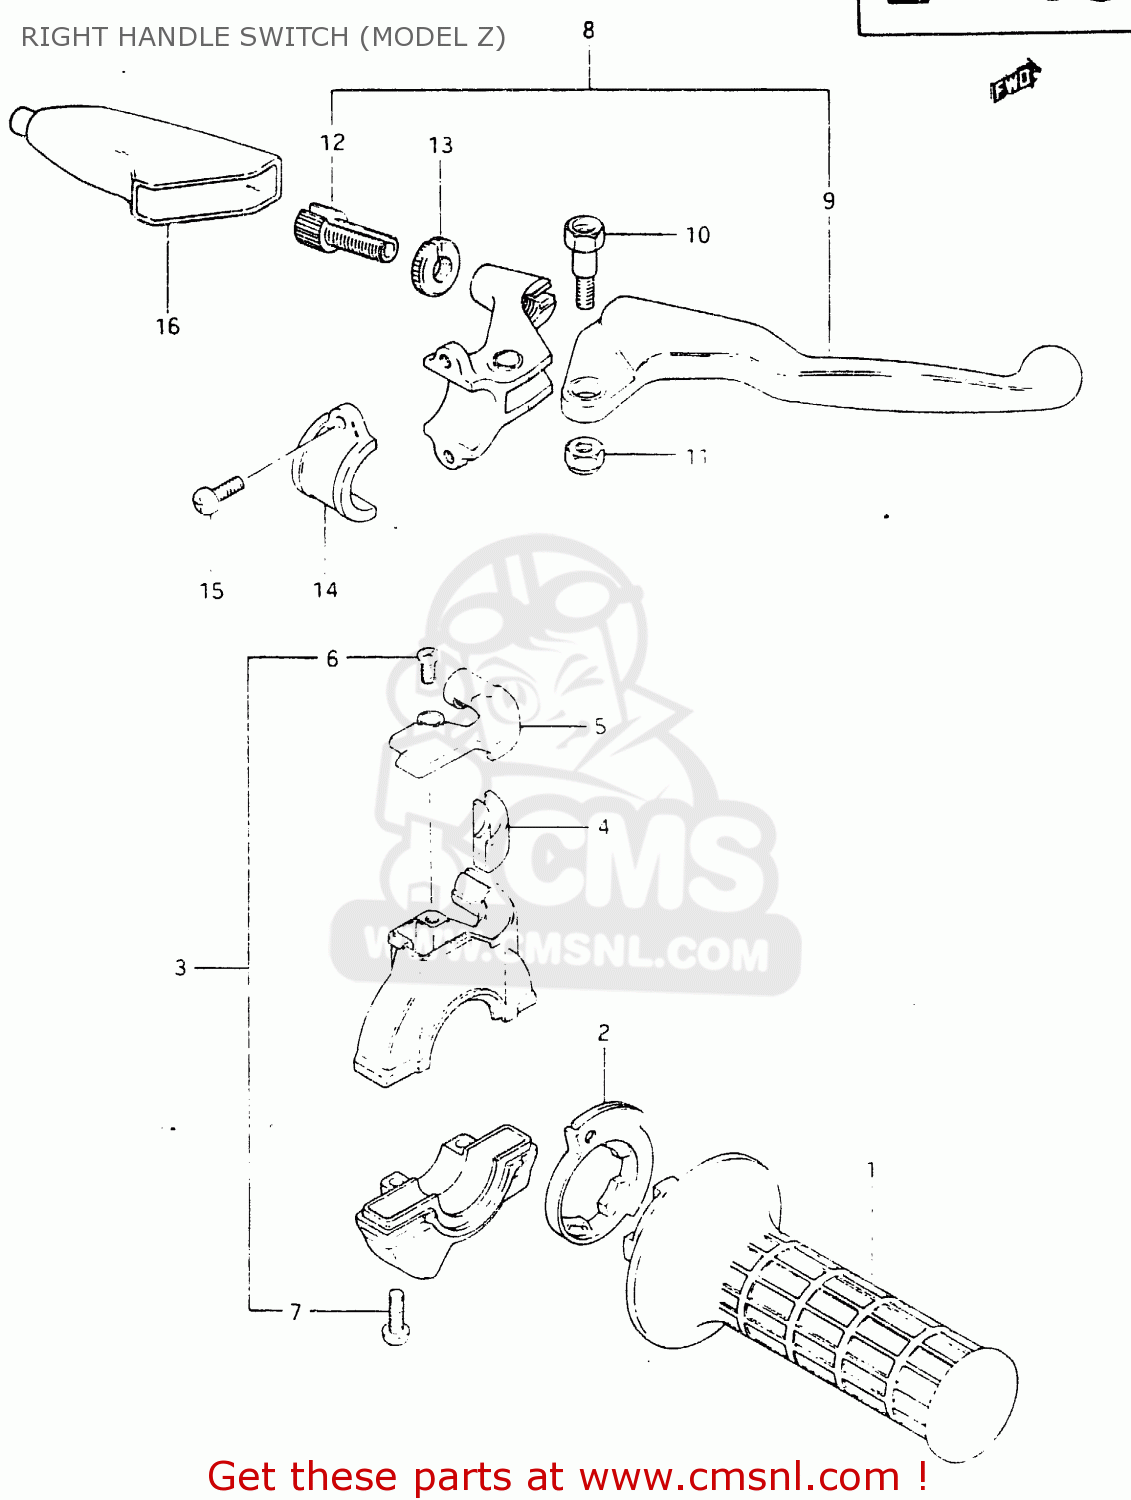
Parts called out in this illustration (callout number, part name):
1	GRIP,THROTTLE
2	ROTOR,THROTTLE GRIP
3	CASE ASSEMBLY,THROTTLE
4	GUIDE PIECE,THROTTLE
5	COVER,THROTTLE CASE
6	SCREW
7	SCREW
8	LEVER ASSEMBLY,BRAKE
9	LEVER,BRAKE
10	BOLT,LEVER
11	NUT 6MM
12	ADJUSTER,CABLE
13	NUT,CABLE ADJUSTER
14	BRACKET,CLUTCH LEVER HOLDER
15	SCREW
16	COVER,CLUTCH LEVER
